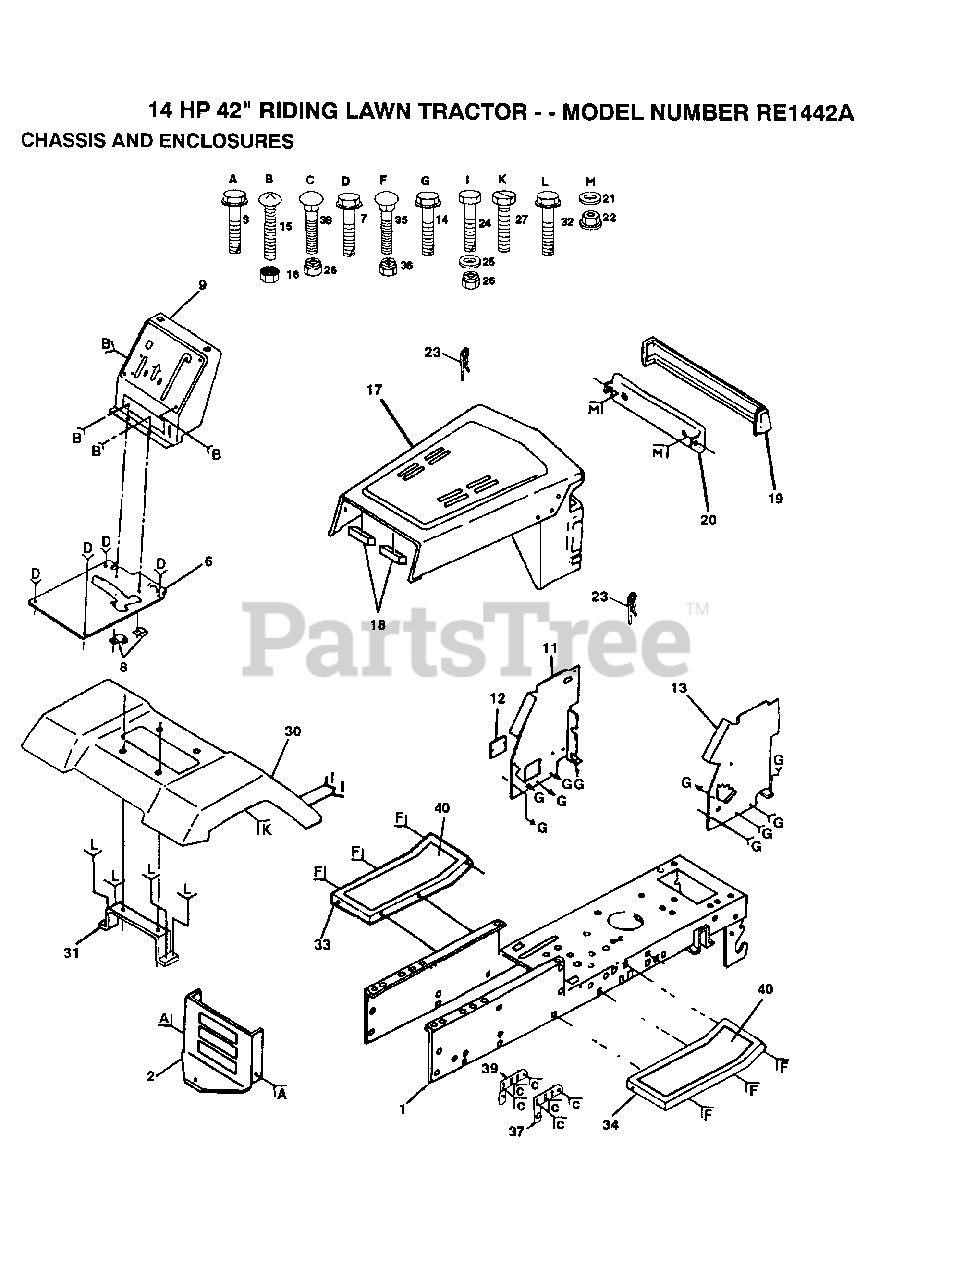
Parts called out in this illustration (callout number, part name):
3	SCREW
7	SCREW LT
8	CLIP T
10	PLUG BUTTON T
11	PANEL DASH LH
12	COVER ACCESS
14	SCREW LT
15	SCREW
17	HOOD/GRILL ASM
21	WASHER PM
22	PAL NUT LT
23	SPRING.RETAINER
25	WASHER
27	SCREW LT
32	SCREW
33	FOOTREST LH
34	FOOTREST
35	BOLT
37	PIVOT BRKT RH
38	BOLT
39	PIVOT BRKT LH
40	"PAD,FOOTREST"
